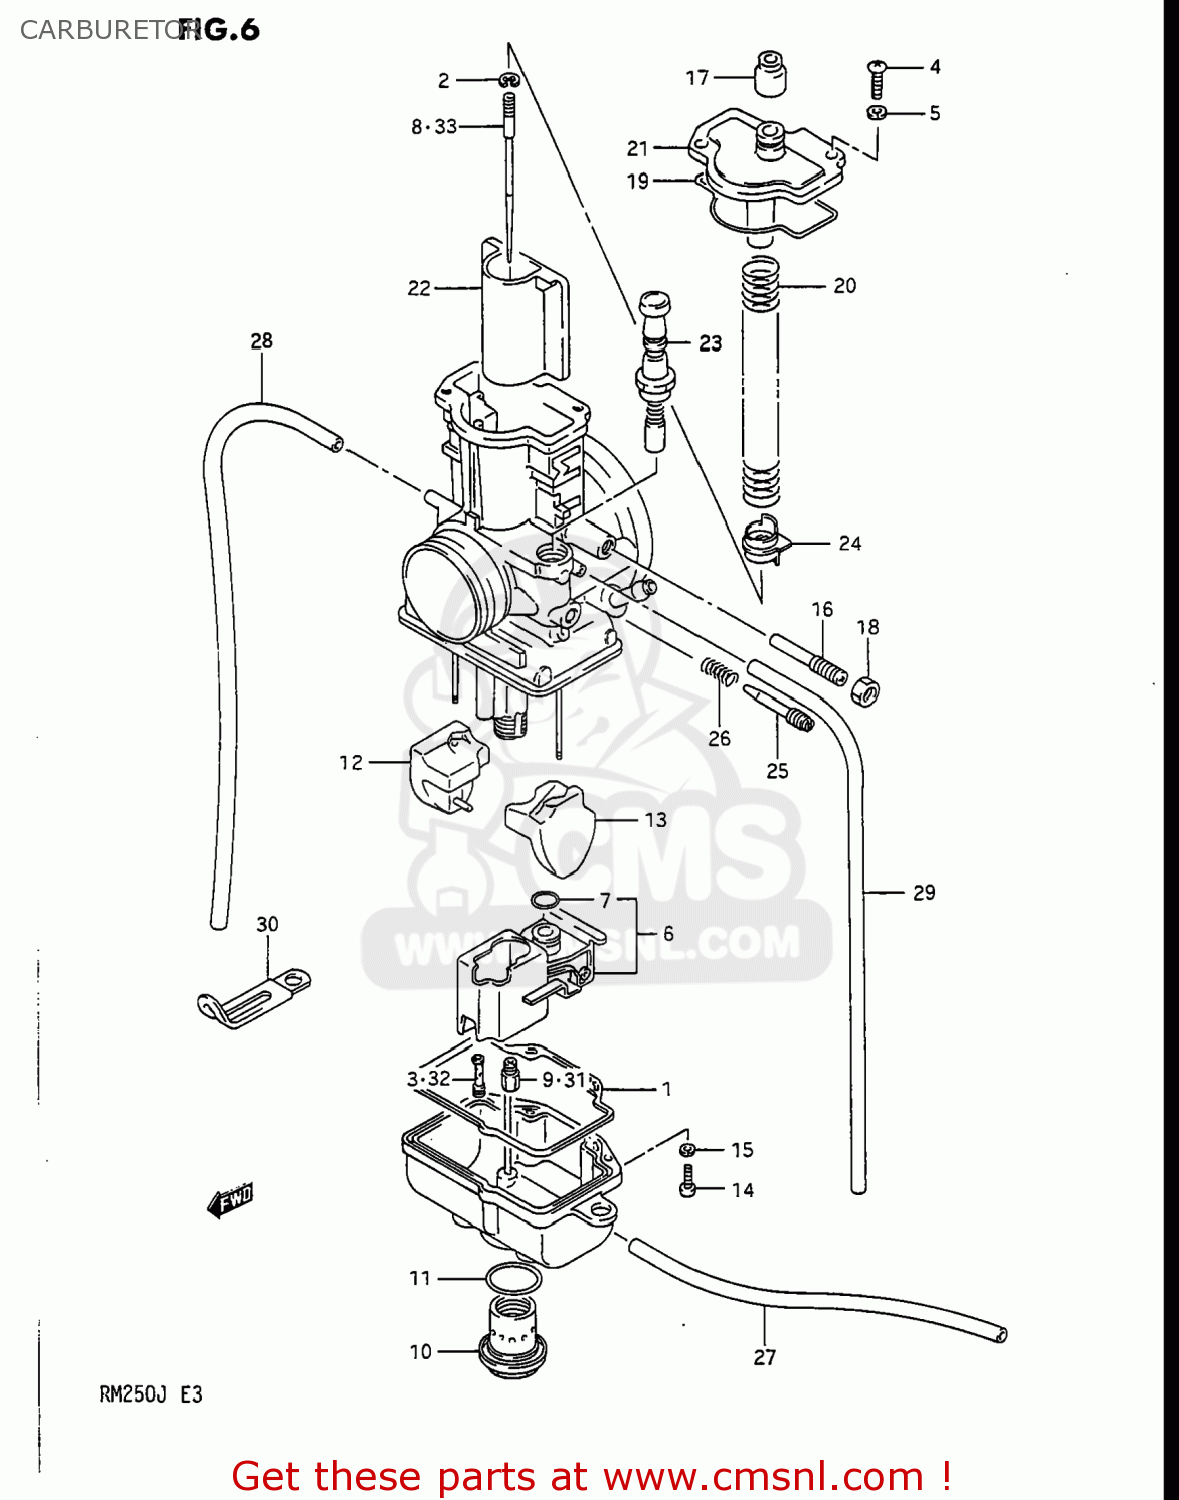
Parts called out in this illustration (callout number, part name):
1	O RING,FLOAT CHAMBER
2	CLIP,NEEDLE
3	JET,PILOT 20
4	SCREW
5	LOCK WASHER
6	VALVE ASSY,NEEDLE
7	O-RING,NEEDLE VALVE
8	NEEDLE JET
9	JET,MAIN(370)
10	CAP,DRAIN
11	O RING,DRAIN PLUG
12	FLOAT,R
13	FLOAT,L
14	SCREW
15	LOCK WASHER
16	ADJUSTER
17	CAP
18	NUT
19	O RING,TOP CAP
20	SPRING
21	CAP,TOP
22	VALVE,PISTON(CA:3.5)
23	PLUNGER ASSY
24	RING
25	SCREW,AIR
26	SPRING
27	HOSE
28	HOSE
29	HOSE
30	CLAMP
31	JET,MAIN(330)
32	JET,PILOT(15)
33	NEEDLE JET (6EJ12-53)
